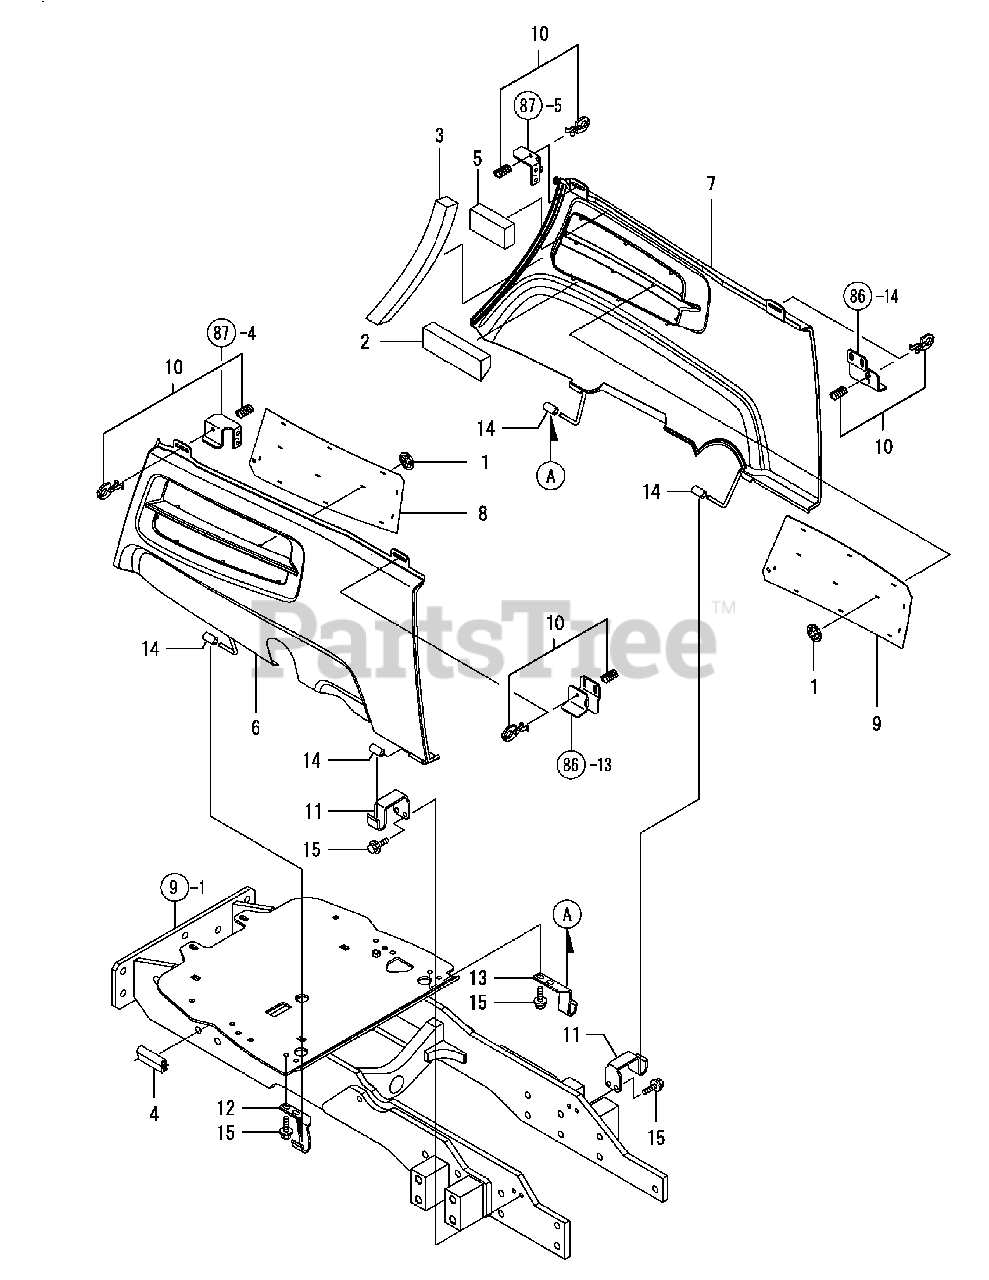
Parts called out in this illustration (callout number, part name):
2	URETHANE, A COVER
3	URETHANE, B COVER
4	WEATHER-STRIP, 440
5	URETHANE, C COVER
6	COVER ASSY, SIDE L.H
7	COVER ASSY,SIDE R.H.
8	NET, L SIDE COVER
9	NET, R SIDE COVER
10	LOCK COMP.,CAM
11	STAY, R SIDE COVER
12	STAY, F SIDE COVER L
13	STAY, F SIDE COVER R
14	RUBBER, CUSHION
15	BOLT M 8X 10 PLATED
